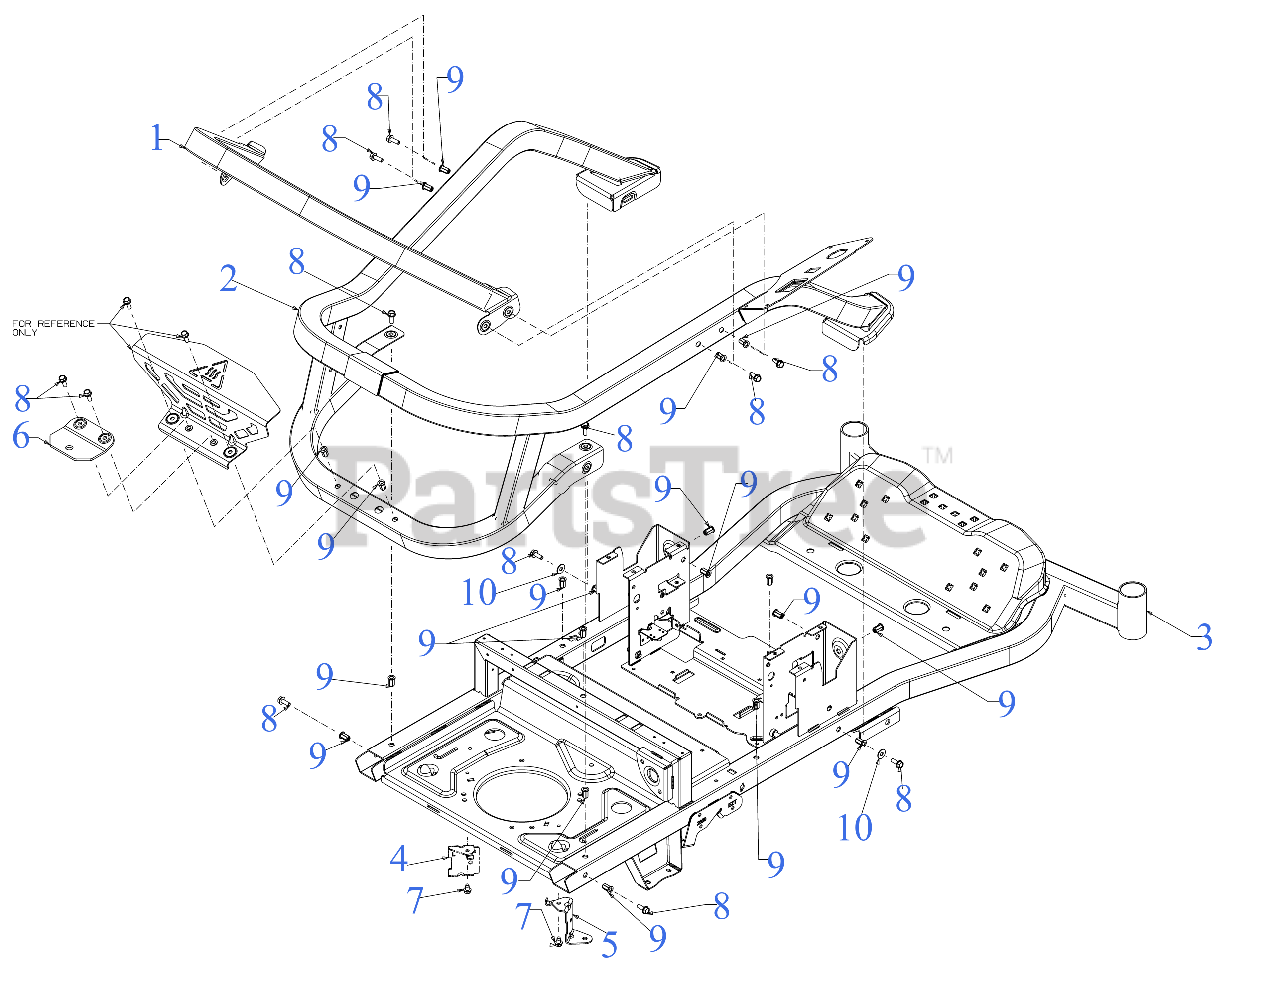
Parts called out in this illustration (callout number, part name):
1	UPPER FRAME HOOP
2	UPPER FRAME
3	FRAME
4	TRANSMISSON MOUNT SUPPORT (LH)
5	TRANSMISSON MOUNT SUPPORT (RH)
6	HITCH PLATE
7	SCREW 5/16-18 x .500
8	SCREW 5/16-18 x .875 GR5
9	NUT RIVET 5/16-18 LOCK
10	FLAT WASHER
